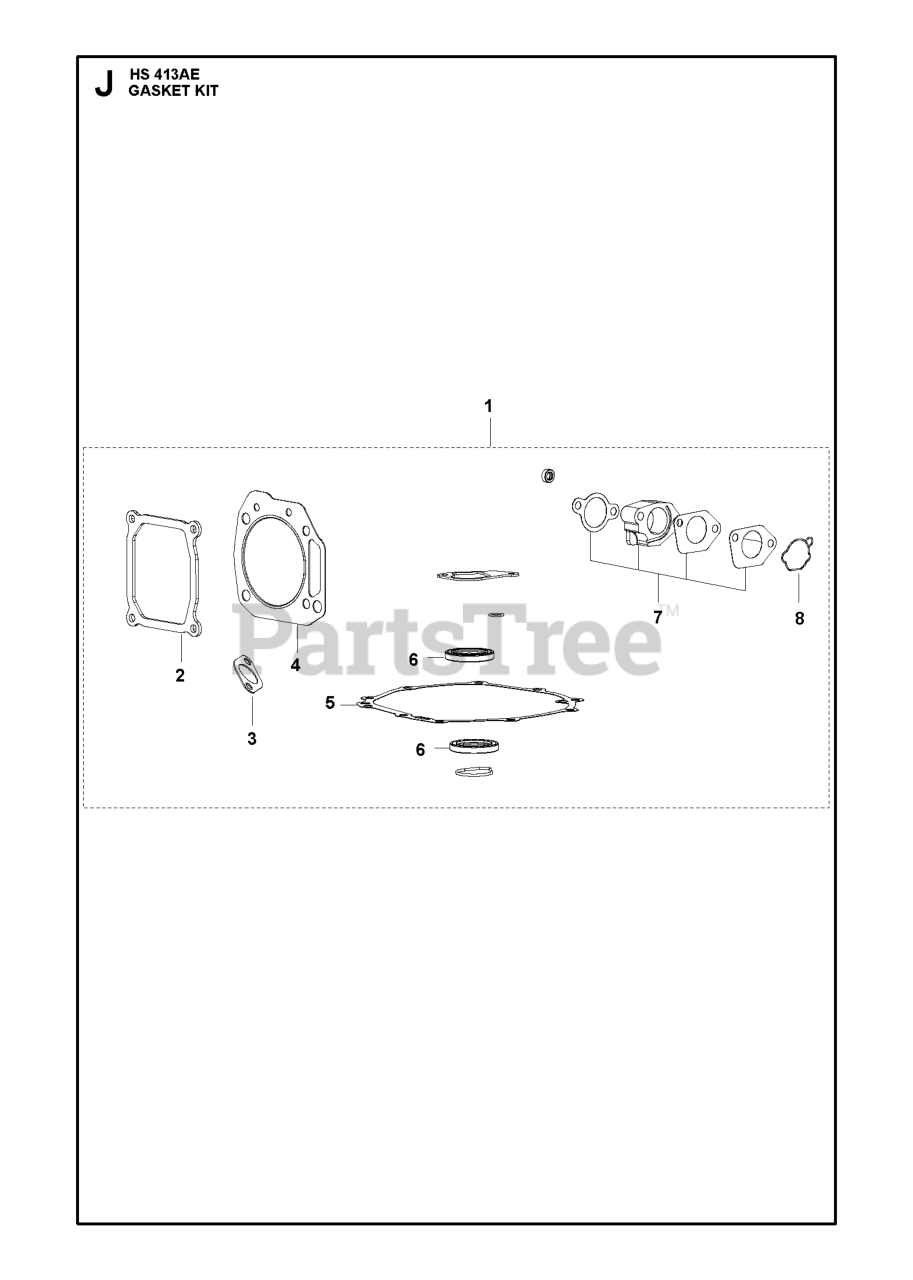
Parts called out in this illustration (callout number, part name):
2	GASKET CYLINDER HEAD COVER GAS
3	EXHAUST GASKET
5	GASKET CRANKCASE COVER GASKET
6	SEAL OIL SEAL
7	GASKET KIT CARBURETTOR GASKET
8	GASKET CARBURETTOR GASKET
